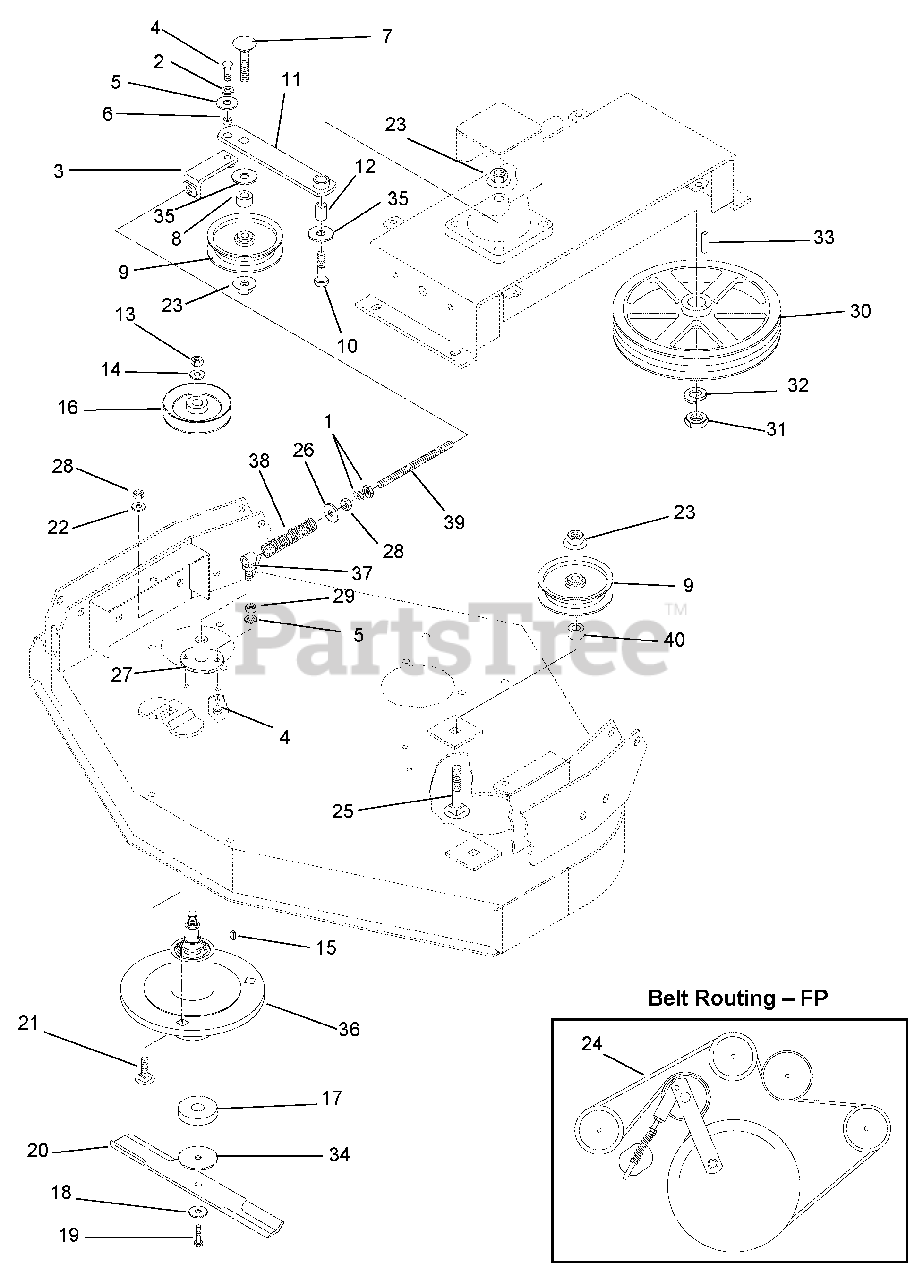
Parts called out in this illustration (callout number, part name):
1	Nut, Jam .50-13
2	Washer, Lock
3	Weldment, Adjustment Rod
4	Cap Screw, Hex Head .38-16 x 1.25
5	Washer, Flat .38
7	Bolt, Carriage .625-11 x 3
8	Spacer .69
9	Assembly, Idler
10	Bolt, Pivot
11	Weldment, Idler Arm
12	Sleeve, Pivot
13	Nut, Lock .625
14	Washer, Flat .625
15	Key, Woodruff #606
16	Sheave 5.50 E.O.D.
17	Washer, Blade
18	Washer, Heavy Duty Safety
19	Cap Screw, Hex Head .50-20 x 1.75
20	Blade, C.W.
21	Bolt, Carriage .50-13 x 1.50
22	Washer, Lock .50
23	Nut, Flange .625-11
24	Belt, HB (115.0)
25	Bolt, Carriage .625 x 4.50
26	Washer, Flat .50
27	Weldment, Pivot Mount
28	Nut, Hex .50
29	Cap Screw, Hex Head .50-20 x 1.75
30	Sheave, Machined 15.16 Diameter
31	Nut, Hex M30 x 2
32	Washer, Spring Outer Tooth
33	Key 6mm x 6mm x 30mm
35	Washer, Flat .625 SAE
36	Spindle Assembly (See See BLADE SPINDLE – FP on page 39.)
37	Weldment, Pivot
38	Spring 1.10 O.D.
39	Rod, Threaded
